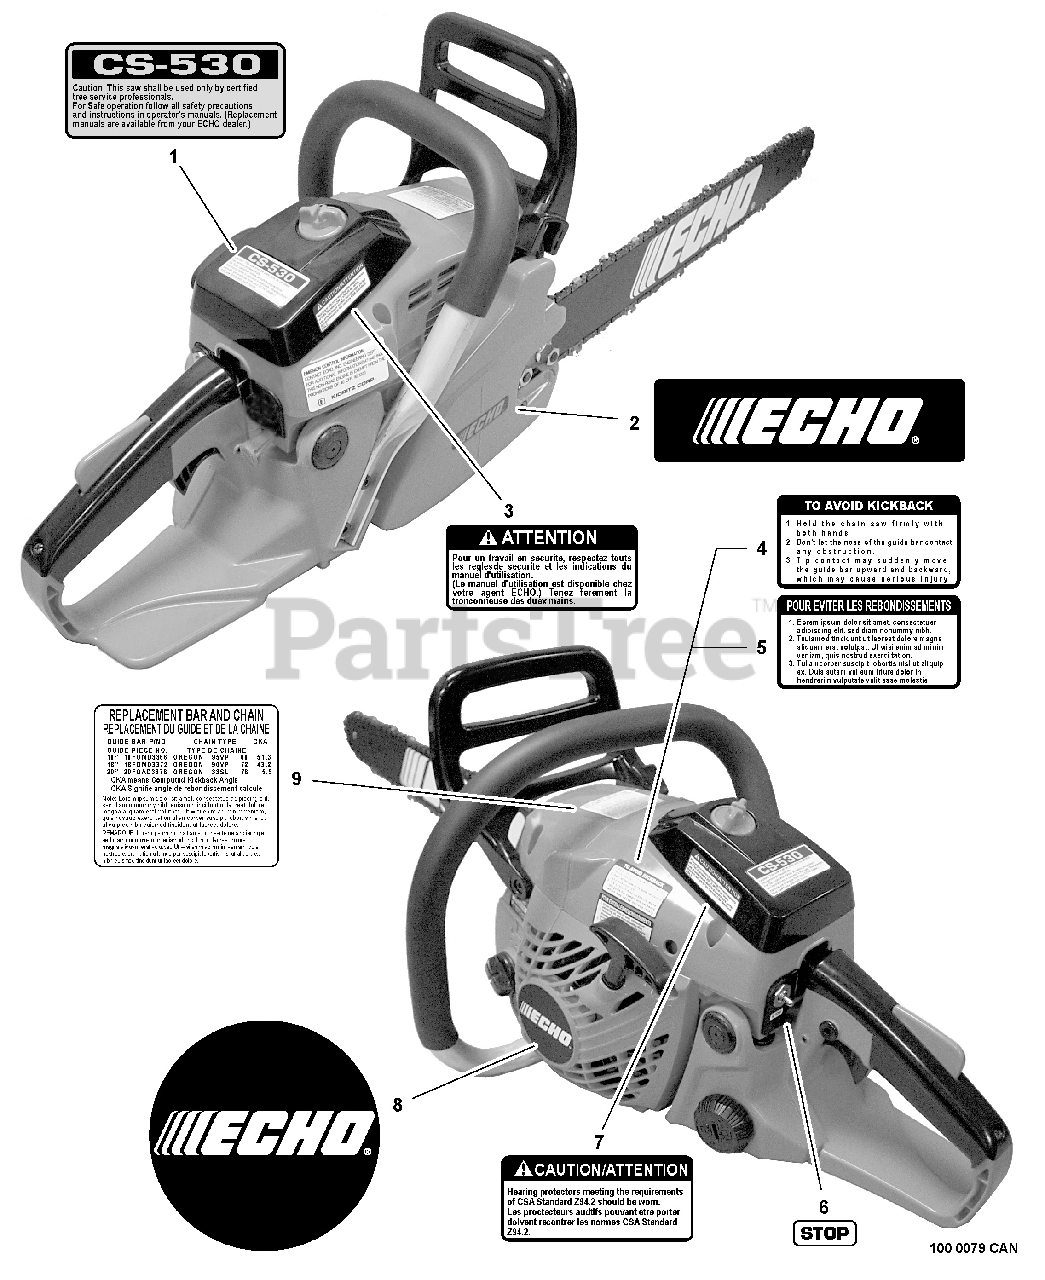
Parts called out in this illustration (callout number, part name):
1	LABEL - MODEL CS-530
2	LABEL - ECHO
3	LABEL - ATTENTION
4	LABEL - KICK BACK
5	LABEL - KICK BACK
6	LABEL - STOP
7	LABEL - NOISE
8	LABEL - ECHO
9	LABEL - BAR & CHAIN
